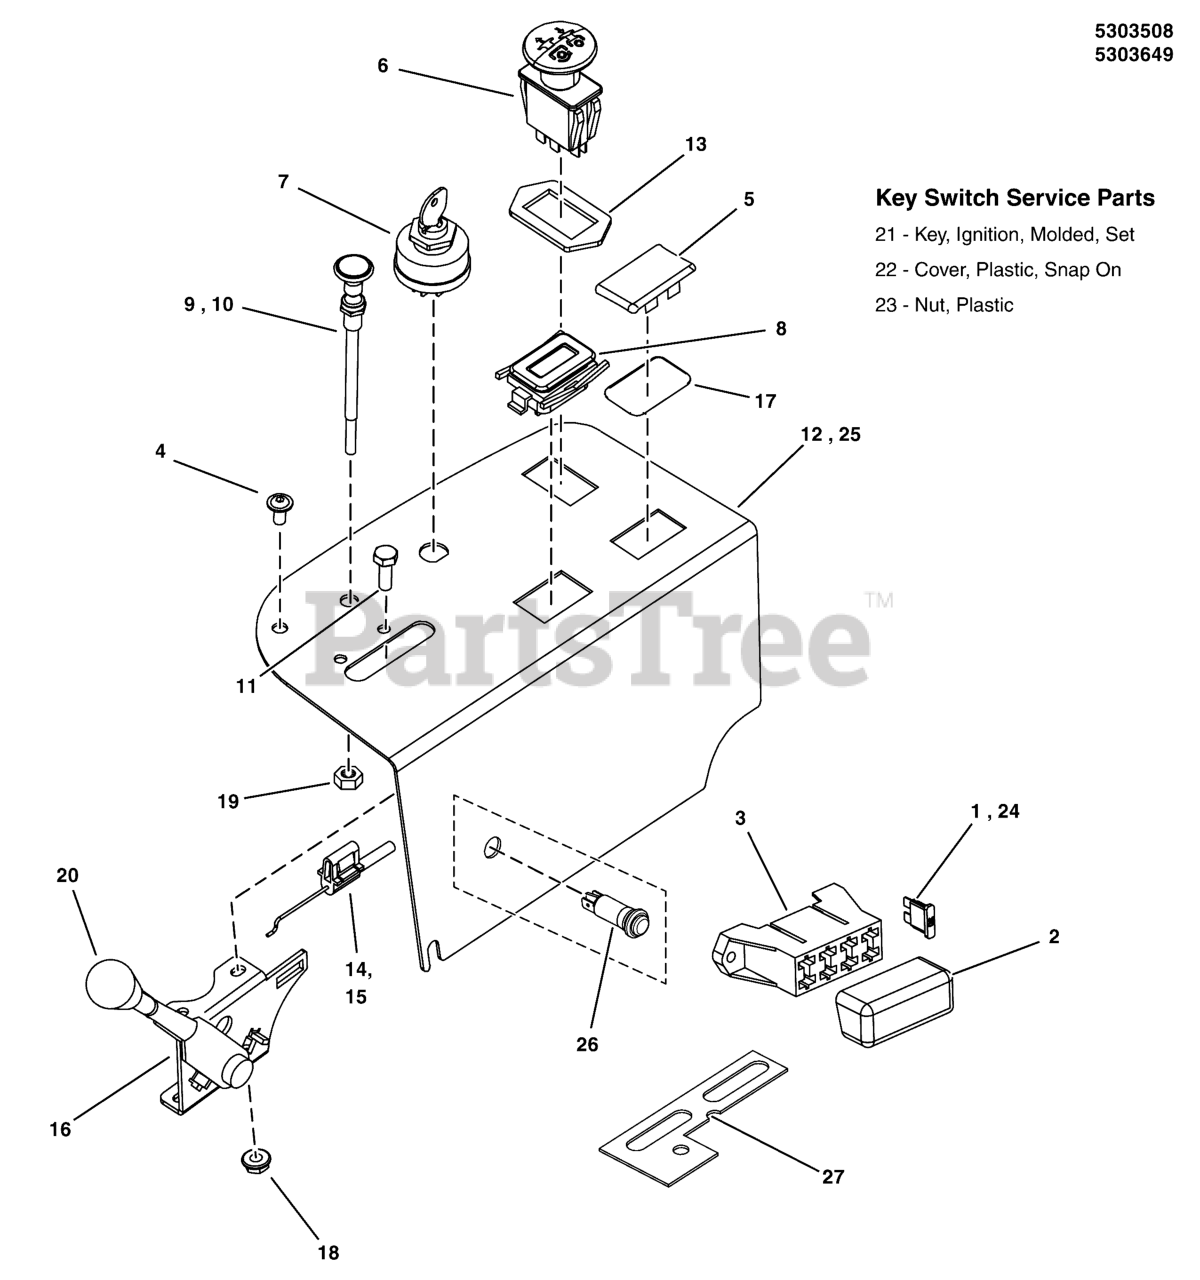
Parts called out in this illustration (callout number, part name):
1	FUSE, ATO, 20 AMP
2	COVER, VINYL FUSEBLOCK
3	FUSE BLOCK
4	SCREW,ALLEN HEAD 1/4-20X.500 ZINC PHOS
5	PLUG, .820X1.44 HOLE, BLACK PLASTIC
6	SWITCH, BLADE ENGAGEMENT
7	SWITCH, IGNITION, 6 POST
8	* HOUR METER, ASSEMBLY
9	CABLE, CHOKE CONTROL, 47
10	CABLE, CHOKE CONTROL, 51 (Z)
11	SCREW, #10-24 X 3/4 ROUND PHILLIPS
12	PANEL, Control - Black
13	RING, SWITCH RETAINER
14	CABLE, THROTTLE, 42"
15	CABLE, THROTTLE 47"
16	LEVER, THROTTLE CONTROL, HEAVY-DUTY
17	O-RING, 7/8 ID X 1/16 W
18	NUT, #10-24 HEX NYLON LOCK
19	NUT, 3/8-24 HEX
20	THROTTLE CONTROL HANDLE/KNOB
21	KEY, IGNITION MOLDED SET
22	COVER, PLASTIC, SNAP ON
23	PLASTIC NUT
24	FUSE, ATO, 15 AMP
25	PANEL, CONTROL, IS2100Z - BLK
26	LIGHT, INDICATOR, PANEL, LED, RED
